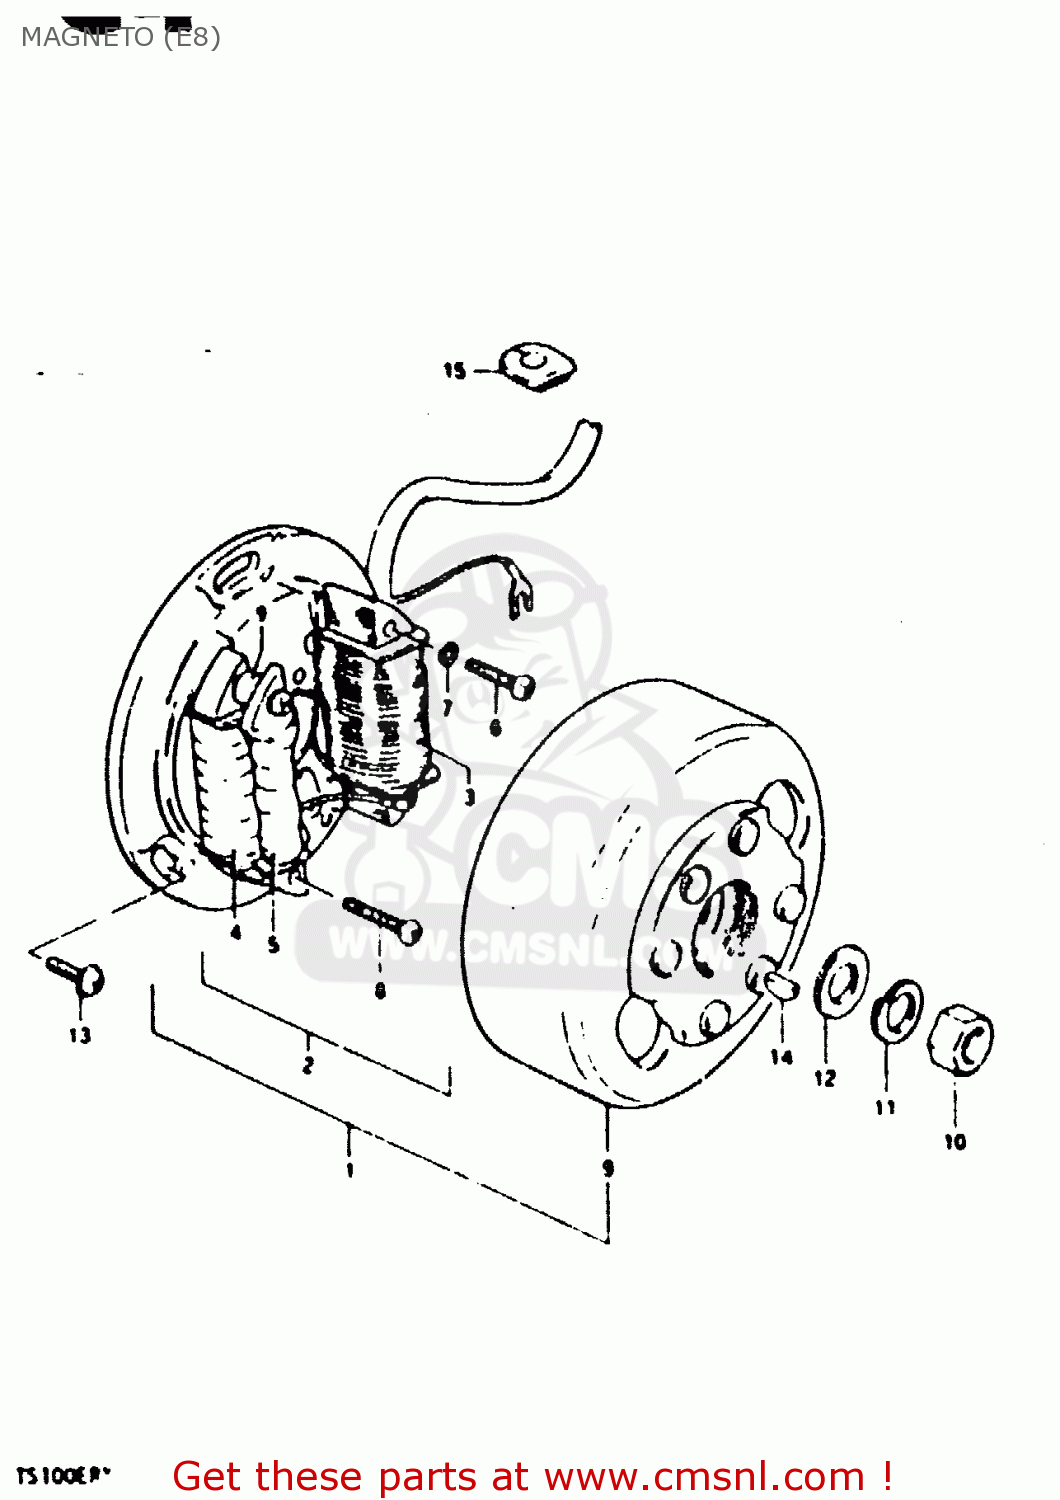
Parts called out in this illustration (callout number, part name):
1	MAGNETO ASSY
2	STATOR ASSY
3	COIL,LIGHTING
4	COIL,PRIMARY
5	COIL,PULSER
6	SCREW 4X25
7	LOCK WASHER
8	SCREW
9	ROTOR
10	NUT (10MM)
11	LOCK WASHER
12	WASHER
13	SCREW(5X14)
14	KEY
15	GROMMET
